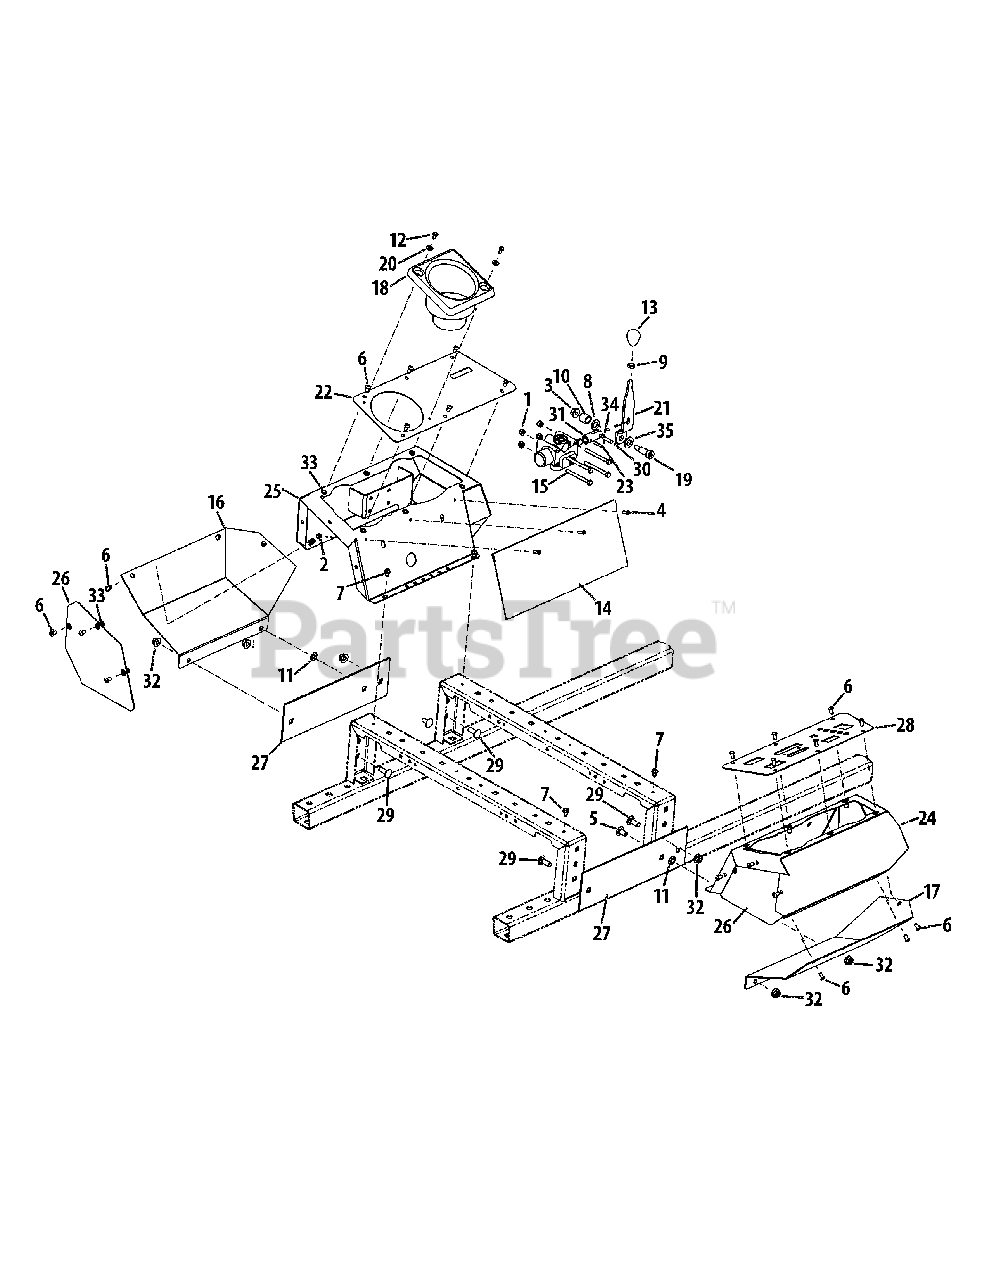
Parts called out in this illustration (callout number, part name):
1	Nut, 1/4-20
2	Nut, #10-32
3	Flange Counter Lock Nut, 3/8-16
4	Machine Screw, #10-32 x .625
5	Carriage Bolt, 3/8-16 x .75
6	Cap Screw, 1/4-20 x .500
7	Hex Flange Screw, 1/4-20 x .500
8	Washer, .536 x .930 x .050
9	Jam Nut, 3/8-16
10	Spacer, .500 x .750 x .700
11	Push Nut, .335 x .780 x .015
12	Flange Screw, #10-32 x .500
13	Lever Knob, 3/8-16
14	Debris/Storage Bag
15	Hex Screw, 1/4-20 x 2.75
16	LH Lower Panel
17	RH Lower Panel
18	Cup Holder
19	Shoulder Bolt, 3/8-16 x .50 x 1.0
20	Washer, .300 x .550 x .047
21	Lift Valve Lever Bracket
22	LH Cover Control Plate
23	Spirol Pin, 3/16 x 1.0
24	RH Contol Panel Assembly
25	LH Bracket Control Panel Assembly
26	Rear Panel Plate
27	Lower Side Panel
28	RH Cover Control Plate
29	Carriage Bolt, 3/8-16 x 1.00
30	Pin, .25 x .9375
31	Valve Link
32	Flange Lock Nut, 3/8-16
33	Rivet Nut, 1/4-20
34	Cotter Pin, 1/16 x .75
35	Bell Washer, .525 x 1.00 x .050
